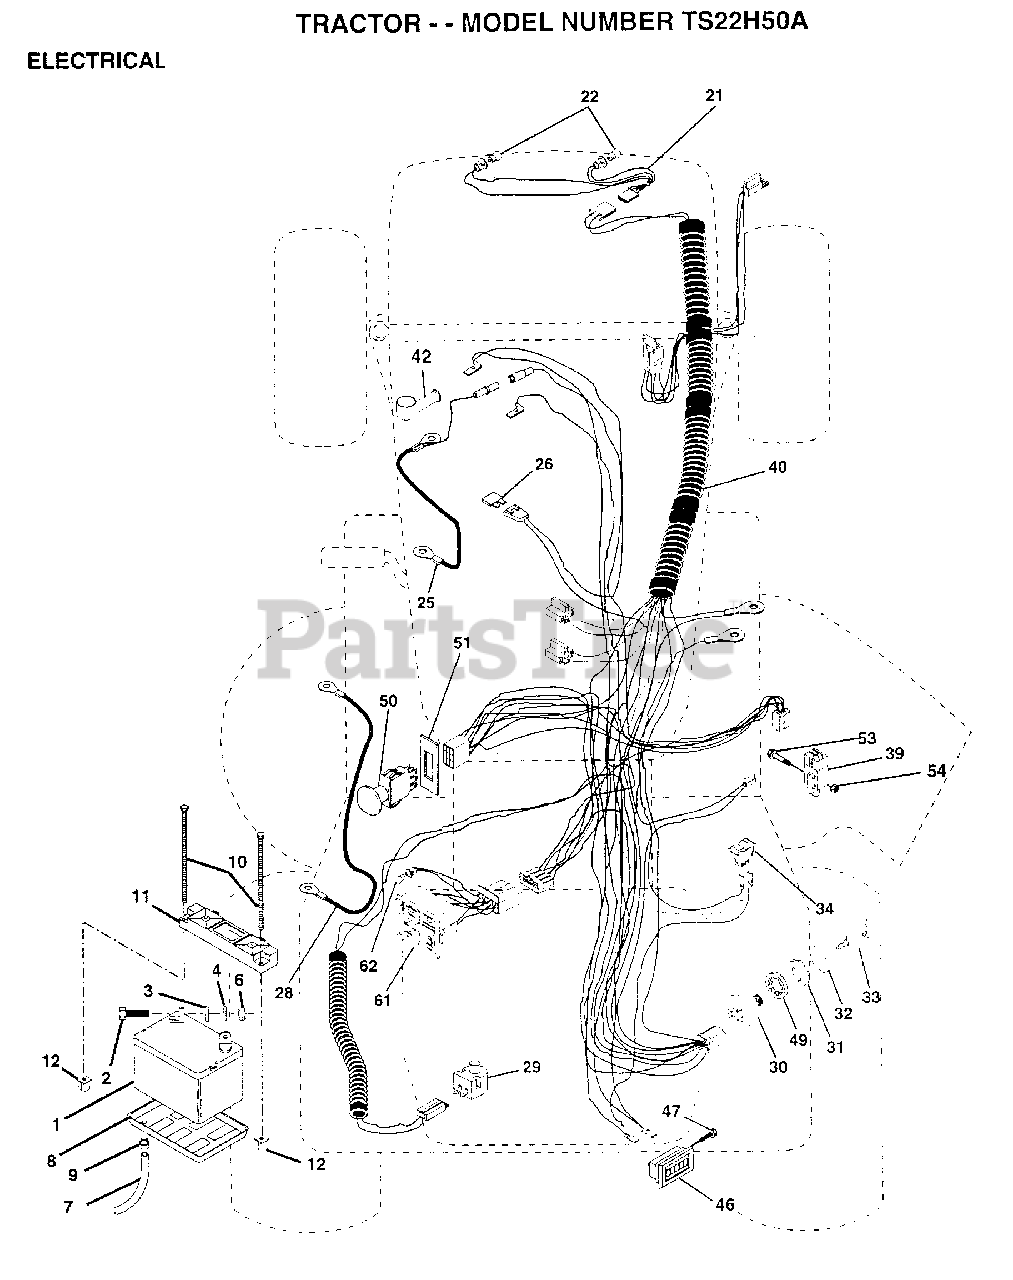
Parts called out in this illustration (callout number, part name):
2	BOLT LT
3	LOCKWASHER
4	WASHER
7	"DRAIN TU T, BATT"
8	"TRAY T, BATTERY"
9	HOSE CLAMP T
21	"HARNESS,LIGHT SOC"
22	HEADLAMP BULB
25	"CABLE-BAT.RED,20"""
26	FUSE HYT
28	CABLE.BATRY.4GA.
29	SWITCH SEAT
30	SWITCH T
31	NUT IGNITION
33	KEY
34	SWITCH LT
39	SWITCH INTERLOCKT
40	"HARNESS,IGNITION"
46	HOUR METER T
47	SCREW
49	LOCKWASHER
51	RING RETAIN PTO
53	SCREW
54	"NUT,KEPS"
61	LIGHT.PKG.ASM.
62	BULB LIGHT T
